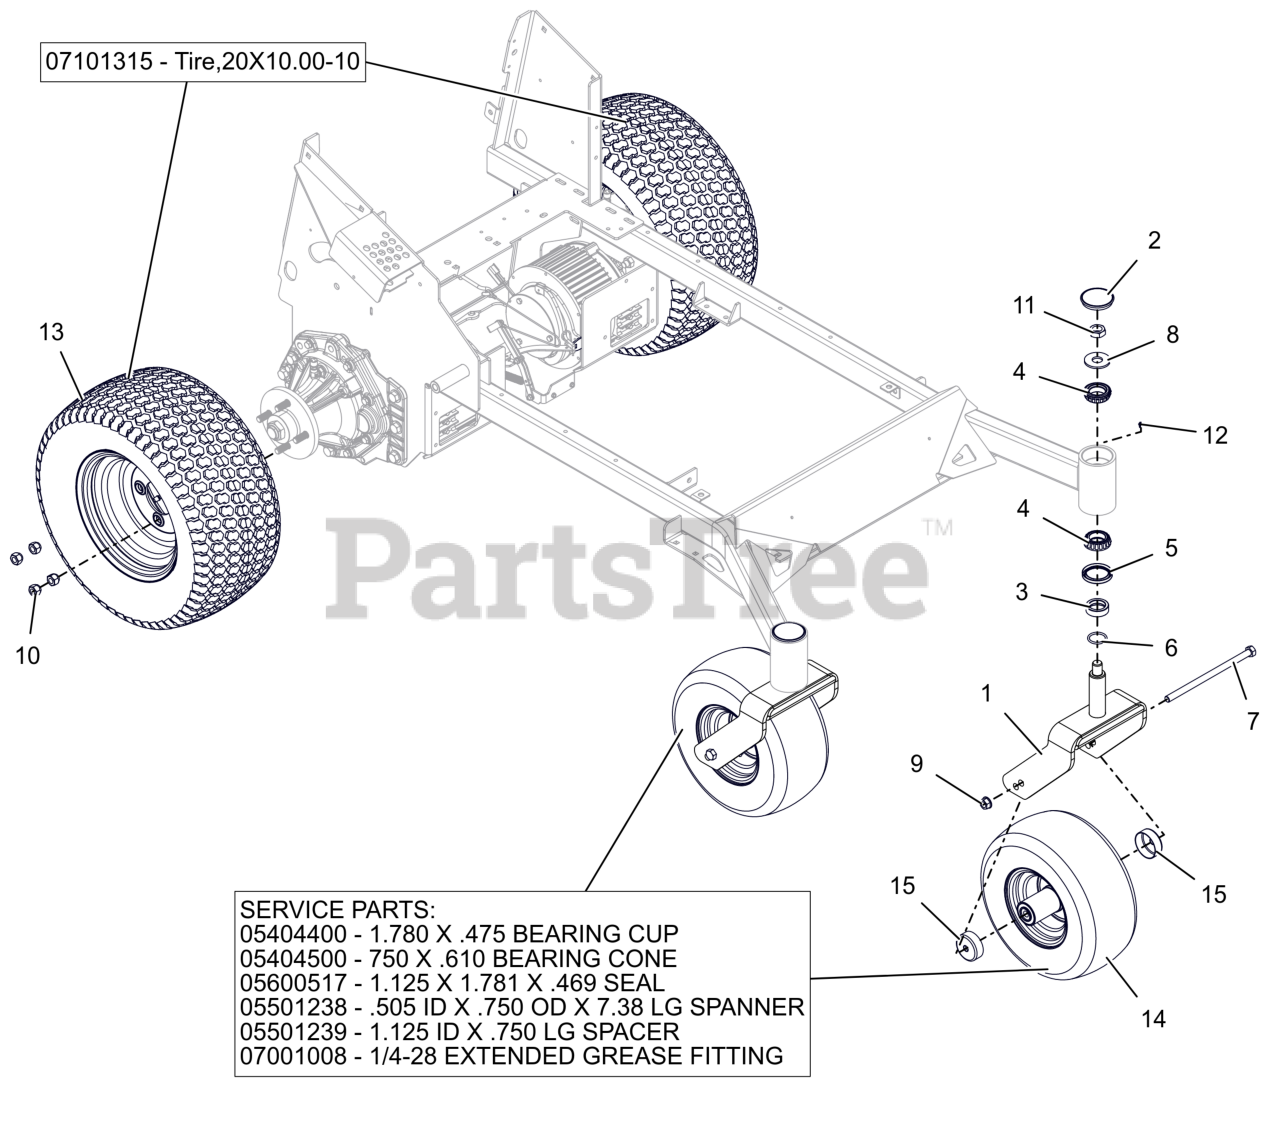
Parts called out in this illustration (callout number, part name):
1	WMT, CASTER FORK (ORANGE)
2	CAP, DUST
3	SPACER SLEEVED CASTER FORK
4	BRG-CONE 1.25X.66
5	SEAL, OIL 1.75 X 2.332 X .312
6	O-RING, .139 W X 1.234 ID
7	BLT, HEX .50-13X9.00 G5 ZCC
8	WSHR, FLT .812X2.000X.148 ZCC
9	NUT-LK-TOP-FLG .500-13 GF ZCC
10	NUT, WHEEL .50-20 ZCC
11	NUT, JAM-TOP LK .750-16 ZCC
12	FTG, .25-28 FLUSH MNT GREASE
13	ASSM TIRE\WHEEL,
13	TIRE, 20X10.00-10 (MONITOR)
14	ASSM TIRE\WHEEL 13X6.50-6 SEMI LOW GLOSS BLACK
14	BRG-CUP 1.781X.475
14	BRG-CONE .750X.61
14	1.125 X 1.7891 X .489 SEAL
14	SPANNER,.505ID X.750OD X7.38LG
14	SPACER, 1.125 ID X .750 LG
14	1/4-28 EXTENDED GREASE FITTING
15	SHIELD, WHEEL BEARING
